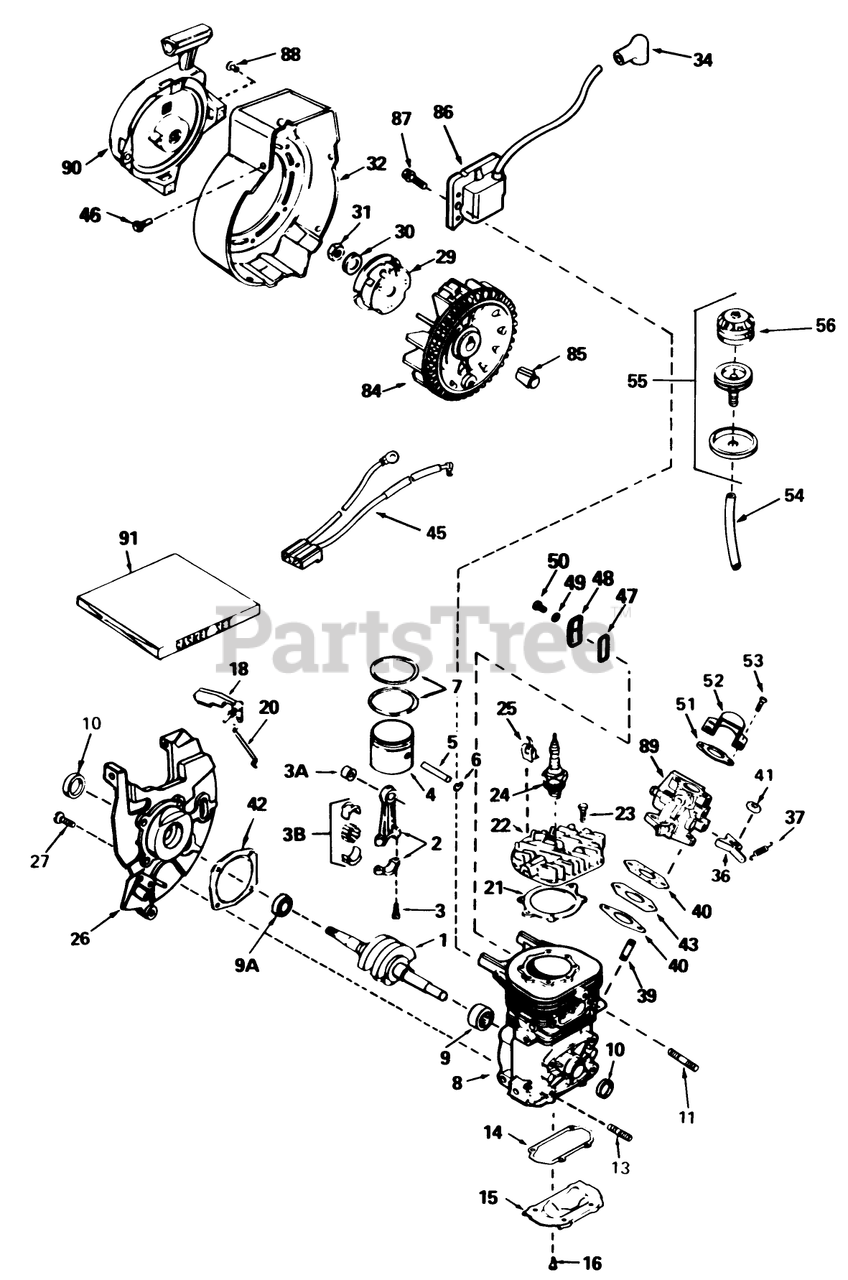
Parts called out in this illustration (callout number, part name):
1	Crankshaft
2	Rod Assy.-Connecting (Incl. Ref. #3, 3A 3B)
3	Bolt-Rod, Connecting
3A	Bearing-Cartridge
3B	Needle Bearing and Liner Set (37 Needles)
4	Piston
5	Pin-Piston
6	Ring-Retaning
7	Ring Set
8	Block Assy.-Cylinder (Order short block if replacement is required.)
9	Bearing-Cartridge
9A	Bearing-Ball
10	Seal-Oil
14	Cover
15	Plate-Cover
16	Screw (T-25, 10-24 x 1/2)
18	Vane-Air
20	Link-Governor
21	Gasket, Head
22	Head-Cylinder
23	Screw (T-30, 1/4-20 x 3/4)
24	Spark Plug-Resistor (R C J 8Y)
26	Base Assy.-Blower Housing (Incl. Ref. #10)
27	Screw (1/4-20x19/32)
29	Cup-Starter
30	Washer-Belleville
31	Nut-Flywheel
32	Housing-Blower
34	Cover-Spark Plug
36	Lever-Adjusting, Rpm
37	Spring-Governor
40	Gasket-Carburetor
41	Locknut
42	Gasket, Shroud Base
43	Spacer
45	Harness-Wire
46	Screw-Hex, Hd.
47	Gasket-Cover
48	Comp. Release Cover
49	Washer
50	Screw (T-25, 10-24 x 1/2)
51	Gasket
52	Baffle-Carburetor
53	Screw
54	Line-Primer
55	Primer Assy.
56	Bulb-Primer
84	Flywheel
85	Blade (20 inch)
86	Solid State
87	Screw
88	Rivet-Pop (3/16" Dia.) (Can be purchased locally)
89	Carburetor (Incl. Ref. #40)
90	Starter-Rewind
91	Gasket Set
